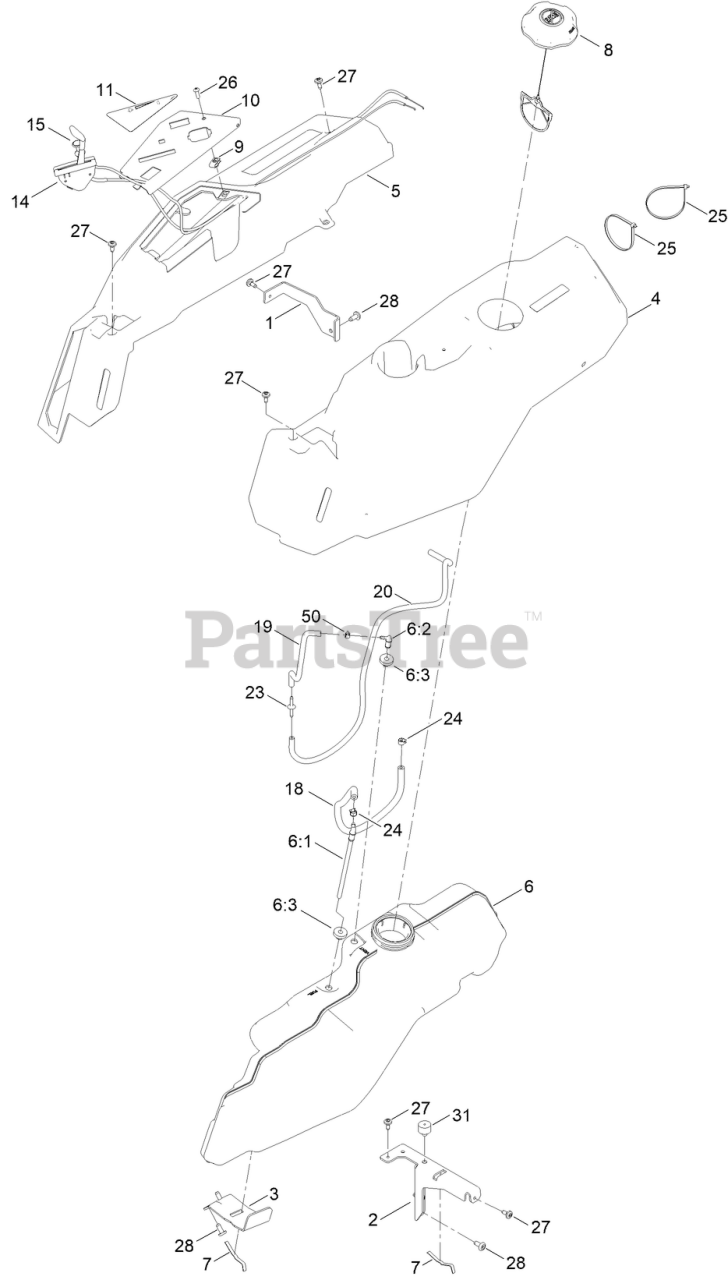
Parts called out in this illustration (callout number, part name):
1	BRACKET-POD
2	SUPPORT-POD, LH
3	SUPPORT-TANK, FUEL
4	POD-LH
5	POD-RH, MYRIDE
6	TANK-FUEL ASM
6:1	CONNECTOR-ELBOW, 90 DEG
6:2	FITTING-ELBOW 90
6:3	BUSHING
7	SPRING
8	CAP-FUEL, RATCHETING
10	PANEL - CONTROL
11	DECAL-PANEL, CONTROL
14	CABLE-THROTTLE
15	CABLE-CHOKE
18	HOSE-FUEL
19	HOSE-FUEL
23	ADAPTER ORIFICE
24	CLAMP-HOSE
25	TIE-CABLE
26	SCREW-PRH
27	SCREW-SHOULDER
31	BUMPER-GROMMET
50	CLAMP-HOSE
